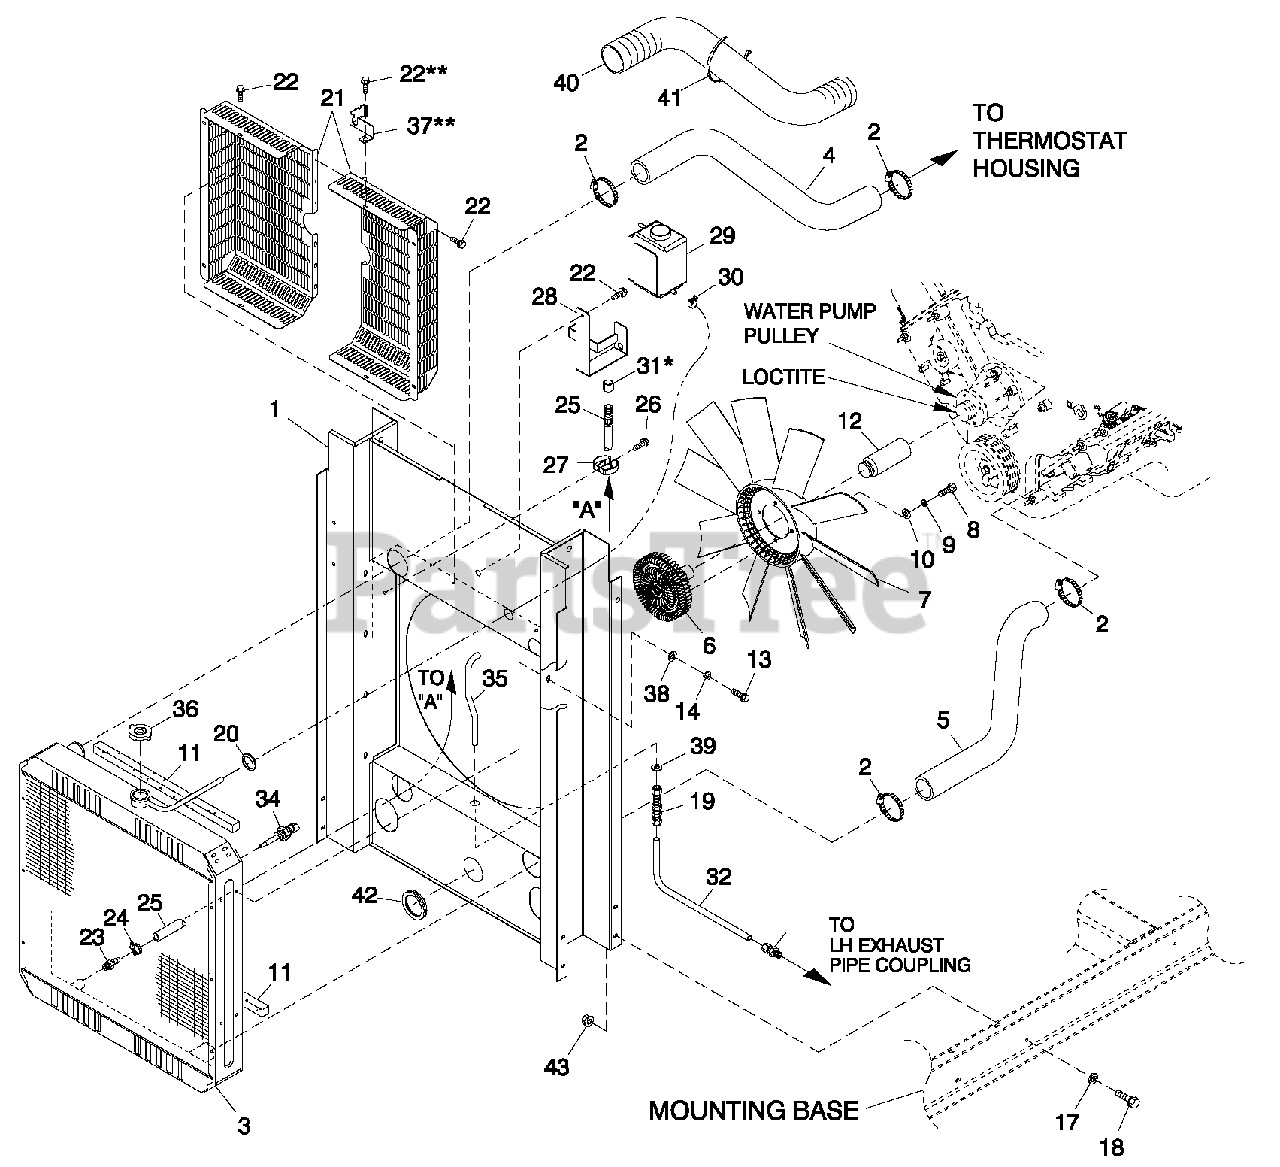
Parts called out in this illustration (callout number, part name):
1	WELDMENT RAD SUPPORT C3 (22")
2	CLAMP HOSE #281.32-2.25
3	RADIATOR 581 X 585 X 70 CPL LH
4	HOSE UPPER RADIATOR C3
5	HOSE LOWER RADIATOR C3
6	CLUTCH COOLING FAN
7	FAN 22" D IA 10 BLADE
8	SCREW HHCM10-1.5X 20 G8.8
9	WASHER LOCK M10
10	WASHER FLAT 3/8-M10 ZINC
11	TAPE FOAM 1 X 1 (23" LG)
12	SPACER FAN 6.8L
13	SCREW HHCM8-1.25X 20 G8.8
14	WASHER LOCK M8-5/16
17	WASHER LOCK M6-1/4
18	SCREW HHFC M6-1.0X20 G8.8
19	FTG CMPN BLKHD 3/8" OD TUBE BRS
20	GROMMET.75X.12X.50
21	GUARD FAN C3 CPL
22	SCREW THF M6-1 X 16 N WA Z/JS
23	BARBED STR 3/8 NPT X 3/8
24	CLAMP HOSE .38-.87
25	HOSE DRAIN ASSY 28"
26	SCREW HHTT M4-0.7X8BP
27	SPRING CLIP HOLDER .37-.62
28	BRKT COOLANT RECOVERY TANK
29	TANK COOLANT RECOVERY
30	CLAMP HOSE BAND 1/4
31	CAP HEX 1/4 NPT BRASS
32	TUBE FAN CLUTCH PREHTR LOWR C3
33	FTG CMPR 3/8TUBE X 3/8 NPT W/FERL
34	PROBE COOLANT LEVEL 3/8NPTF (USE WITH HARN P/N 0F5990 & 0F5991)
35	TUBE FAN CLUTCH PREHTR UPPR C2
36	CAP RADIATOR 13 PSI
37	BRACKET SIGNAL CONDITIONER
38	WASHER FLAT 5/16-M8 ZINC
39	WASHER FLAT 9/16 ZINC
40	CONDUIT FLEX 2.0"ID
41	TIE WRAP UL 14.6 X .14 BLK
42	GROMMET 1.37 X .0 6 X 1.00
43	NUT FLANGE M6-1.0NYLOK
